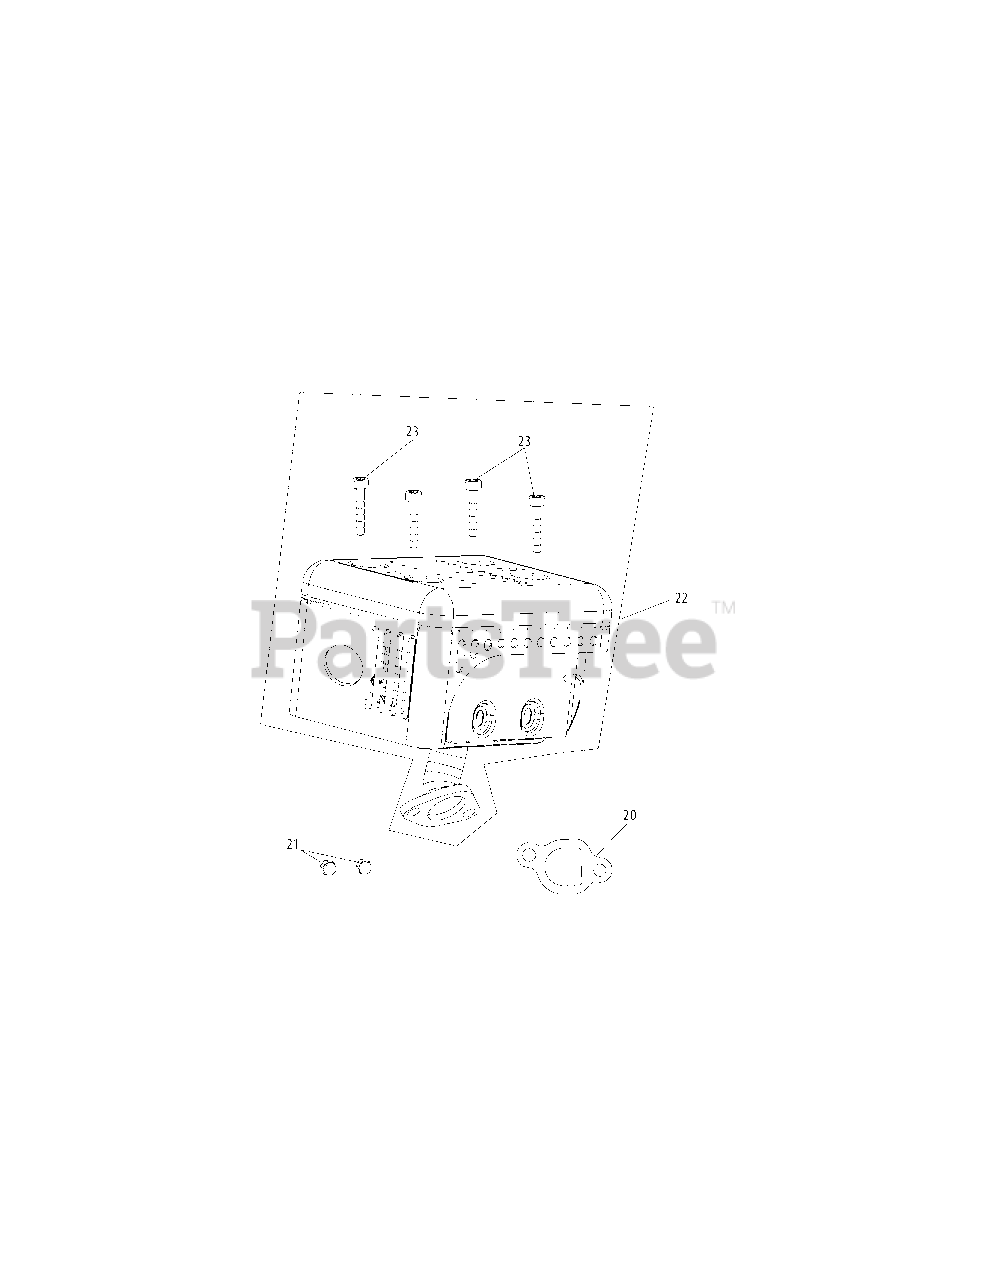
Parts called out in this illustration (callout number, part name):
20	Exhaust Pipe Gasket
22	Muffler Assembly
23	Bolt M5×10
